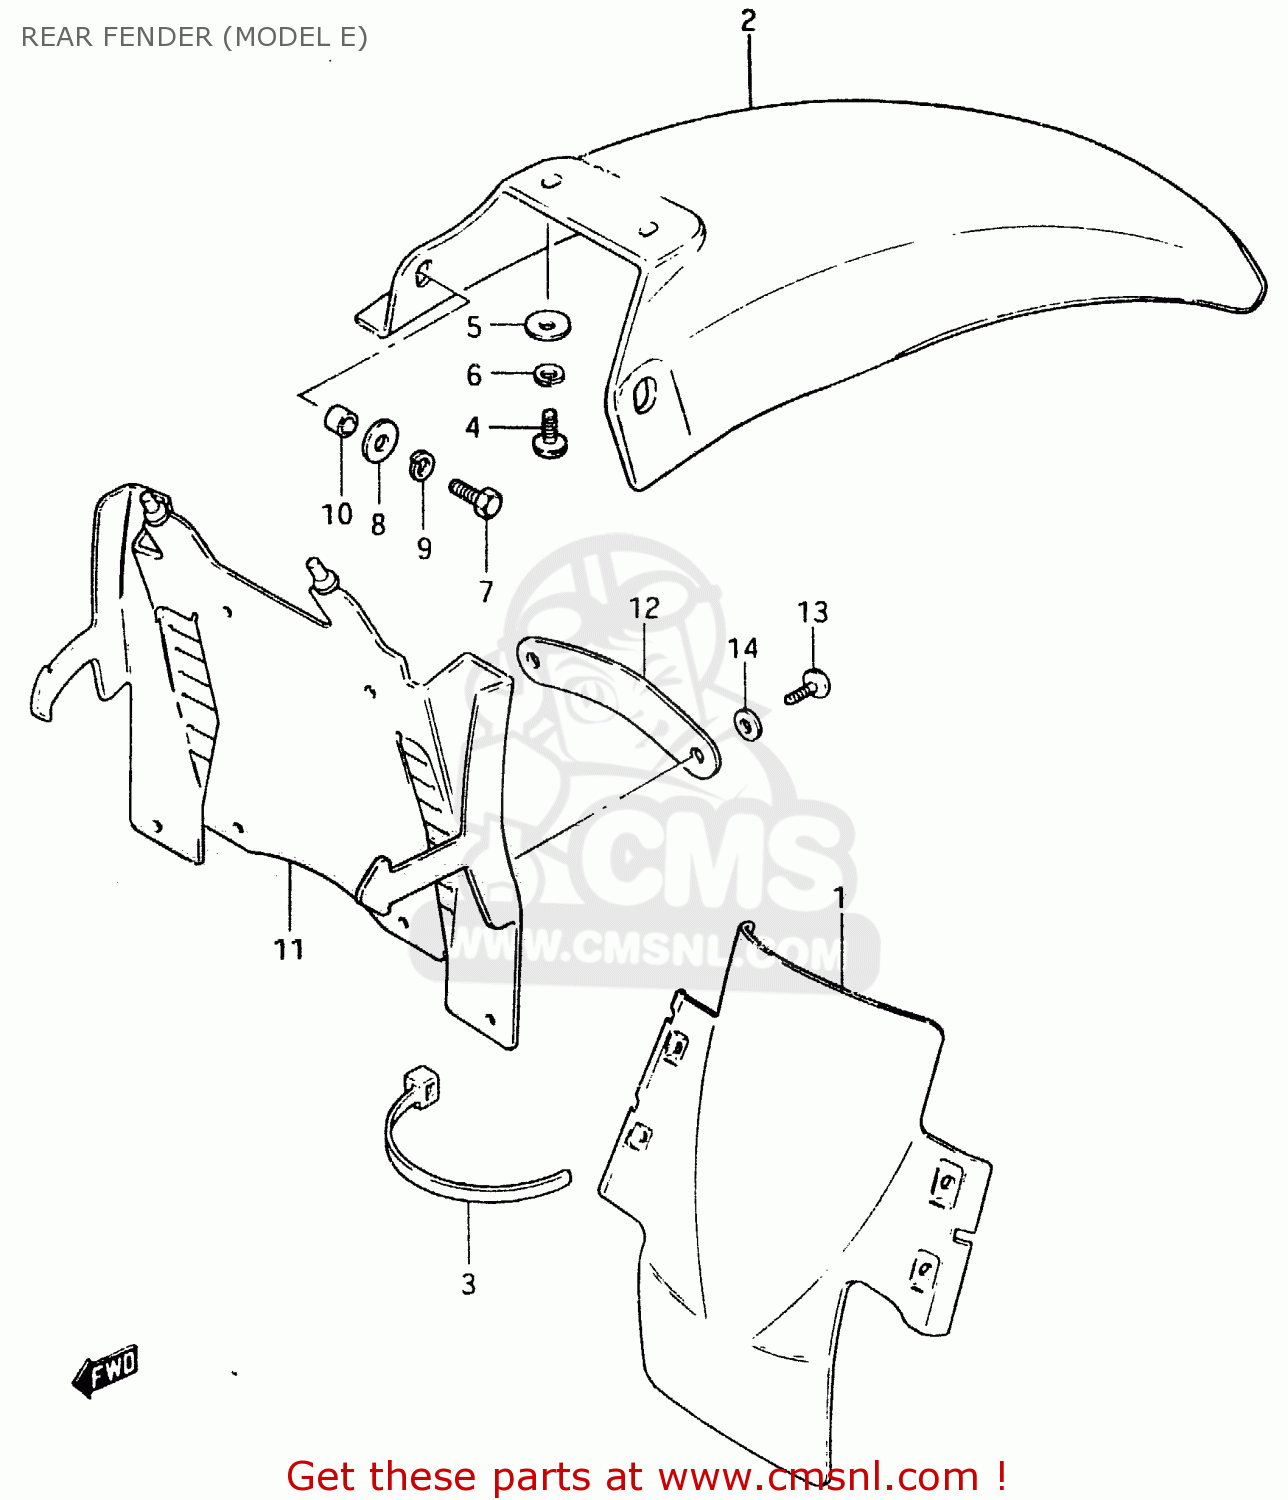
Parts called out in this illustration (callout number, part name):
1	REAR FENDER,FRONT
2	FENDER,REAR
3	CLAMP
4	SCREW
5	WASHER (6.5X20X1.2)
6	LOCK WASHER
7	BOLT, UPPER
8	WASHER (6.5X20X1.2)
9	LOCK WASHER
10	SPACER
11	MUD GUARD,REAR FENDER
12	PLATE,MUD GUARD
13	SCREW
14	WASHER,5MM
